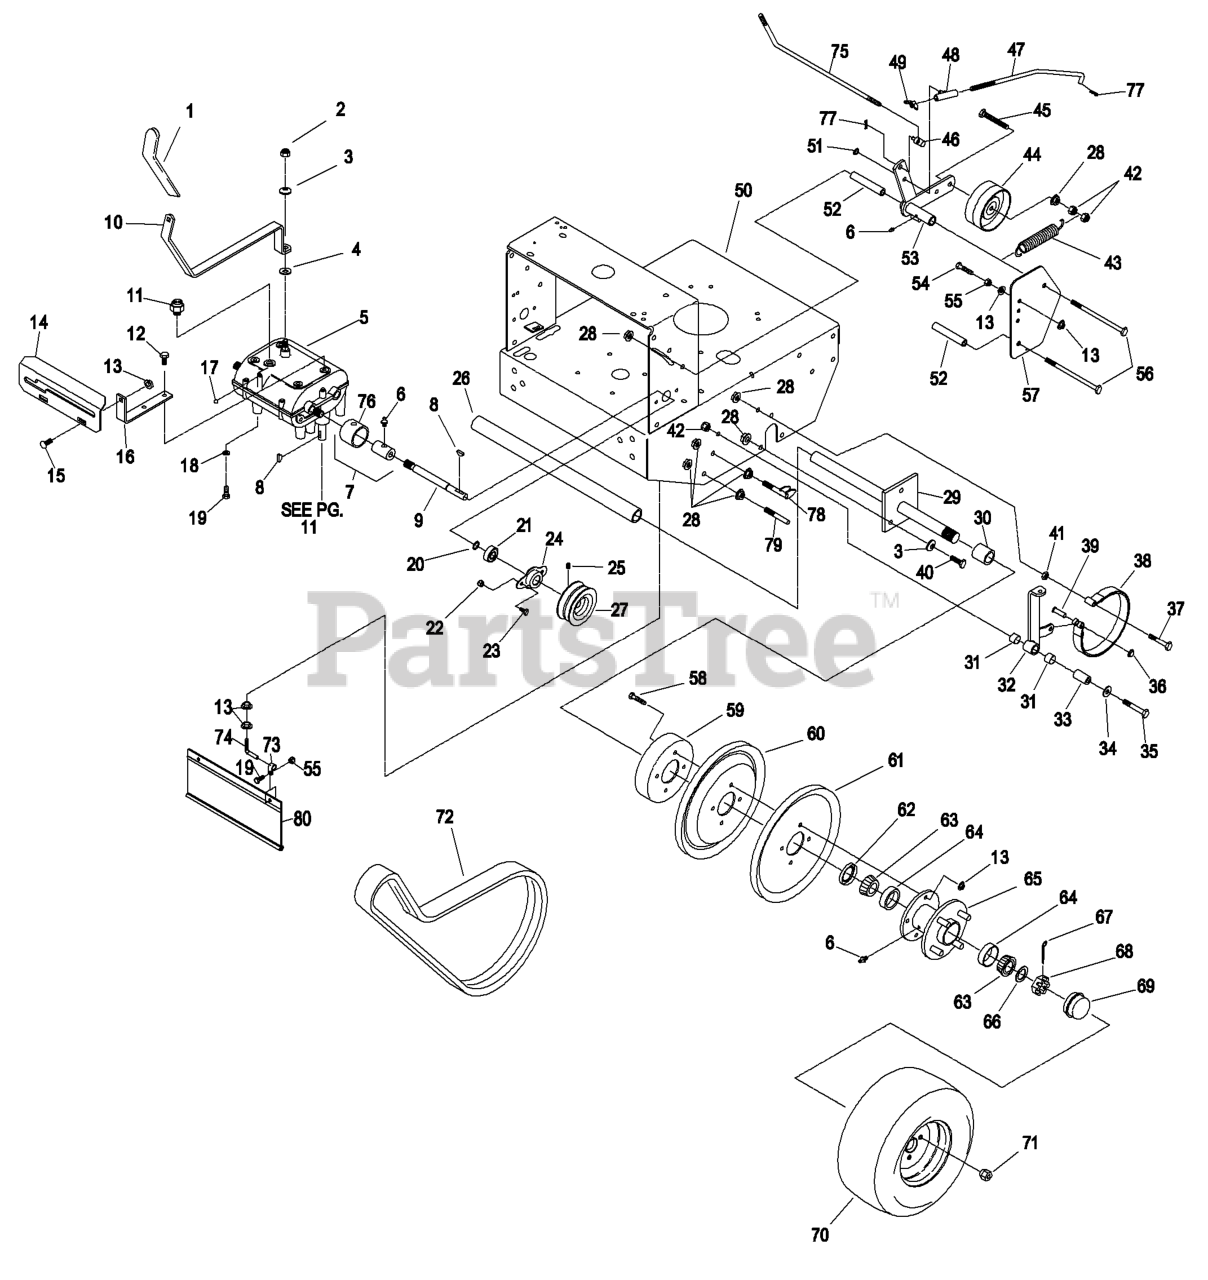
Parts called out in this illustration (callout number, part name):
1	GRIP,FOAM
2	NUT-LOCK
3	WASHER-BELLEVILLE
6	FITTING-GREASE
7	ASM,COUPLER/ZERK
8	KEY-WOODRUFF
9	SHAFT-TRANSMISSION
10	ASM,SHIFT LEVER
11	SWITCH-START, NEUTRAL
12	SCREW-HWH, THREAD CUT
15	BOLT-CARR
16	BRACKET-PLATE, SHIFT
17	BALL,DETENT (SERVICE ONL
18	WASHER-LOCK
19	SCREW-HH
20	RING-RETAINING
21	BEARING-SHAFT
22	NUT-LOCK, NI
23	SCREW-HH
24	FLANGE-OUTPUT
25	SCREW-SET
26	SLEEVE,AXLE
28	NUT-HHF, WHIZ
30	SPACER,WHEEL SHORT
31	SLEEVE-BUSHING
32	ASM,RH BRAKE LEVER W/BSHG
33	BUSHING-PIVOT
34	WASHER-FLAT
35	SCREW-HH
36	RING-RETAIN,PUSH,EXT,FLAT
37	SCREW-HH
38	BAND-BRAKE
39	PIN-CLEVIS
40	SCREW-HH
41	NUT-JAM
42	NUT-LOCK, NI
43	SPRING-EXTENSION
44	IDLER-WHEEL, DRIVE
45	SCREW-HH
46	SWIVEL-DRIVE LEVER, 3/8 L
49	WINGNUT-NYLOCK
51	RING-RETAINING
52	SPACER-SHIELD
53	WLD,RH IDLER ARM
54	SCREW-HH
55	NUT-LOCK, NI
56	SCREW-HH
57	SHIELD,WHEEL DRIVE
58	SCREW-HH
59	DRUM-BRAKE
60	SHEAVE,WHEEL DRIVE
61	SHEAVE,WHEEL DRIVE
62	SEAL-GREASE
63	Cone-Bearing Tapered Roller
64	CUP-BEARING
65	HUB/WHEEL ASM
66	WASHER-SPACER
67	PIN-COTTER
68	NUT-SHH
69	CAP-GREASE
70	WHEEL AND TIRE ASM
71	NUT-LUG
72	BELT,WHEEL DRIVE BANDED
73	CLIP-LOOM
74	MOUNT,DRAG SHIELD
75	LINKAGE,DRIVE (PLT)
76	GUARD-COUPLER
77	PIN-COTTER
78	SCRAPER
80	SHIELD-TRAILING
